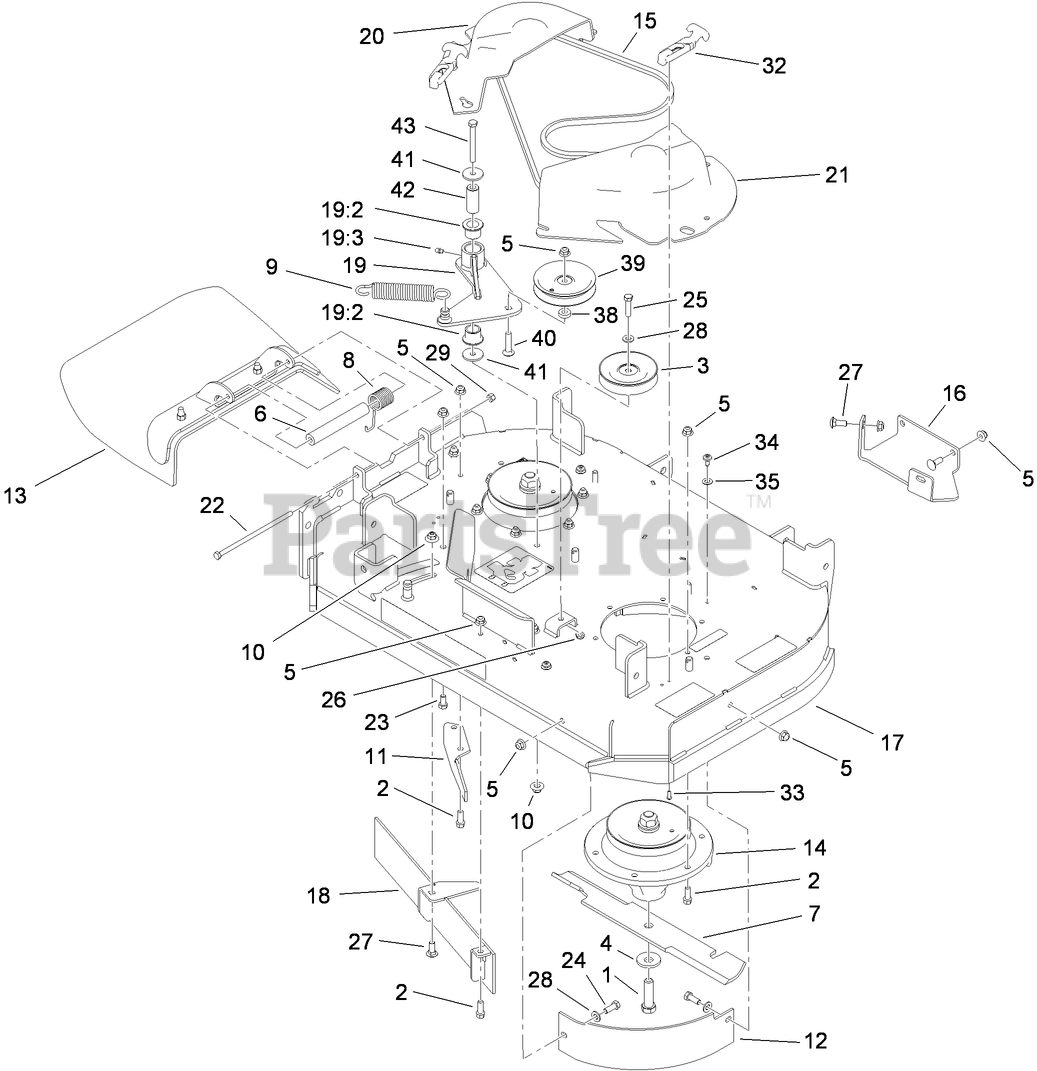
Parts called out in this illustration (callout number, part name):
1	SCREW-BLADE
2	SCREW-HWH
3	PULLEY-IDLER
4	Washer-Blade Bolt, Heavy
5	NUT-HF, NI
6	SPACER
7	BLADE-18IN, HI FLOW
8	SPRING-TORSION
9	SPRING-EXTENSION
10	NUT-FLANGE, NI
11	BAFFLE-DISCHARGE
12	BAFFLE-FRONT, LH
13	DEFLECTOR ASM
14	SPINDLE ASM
15	BELT-V
16	PLATE-SKID
17	DECK ASM
18	FRONT BAFFLE ASM
19	IDLER ARM ASM
19:2	BUSHING
19:3	FITTING-GREASE
20	COVER-BELT, RH
21	COVER-BELT, LH
22	SCREW-HH
23	SCREW-HH
24	SCREW-HH
25	SCREW-HH
26	NUT-LOCK, NI
27	BOLT-CARR
28	WASHER-FLAT
29	NUT-LOCK, NI
32	LATCH-RUBBER
33	SCREW-HSBH
34	SCREW-SHOULDER
35	WASHER-THRUST
38	SPACER
39	PULLEY-IDLER
40	SCREW-CARR
41	WASHER
42	SPACER-PLAIN
43	SCREW-HH
